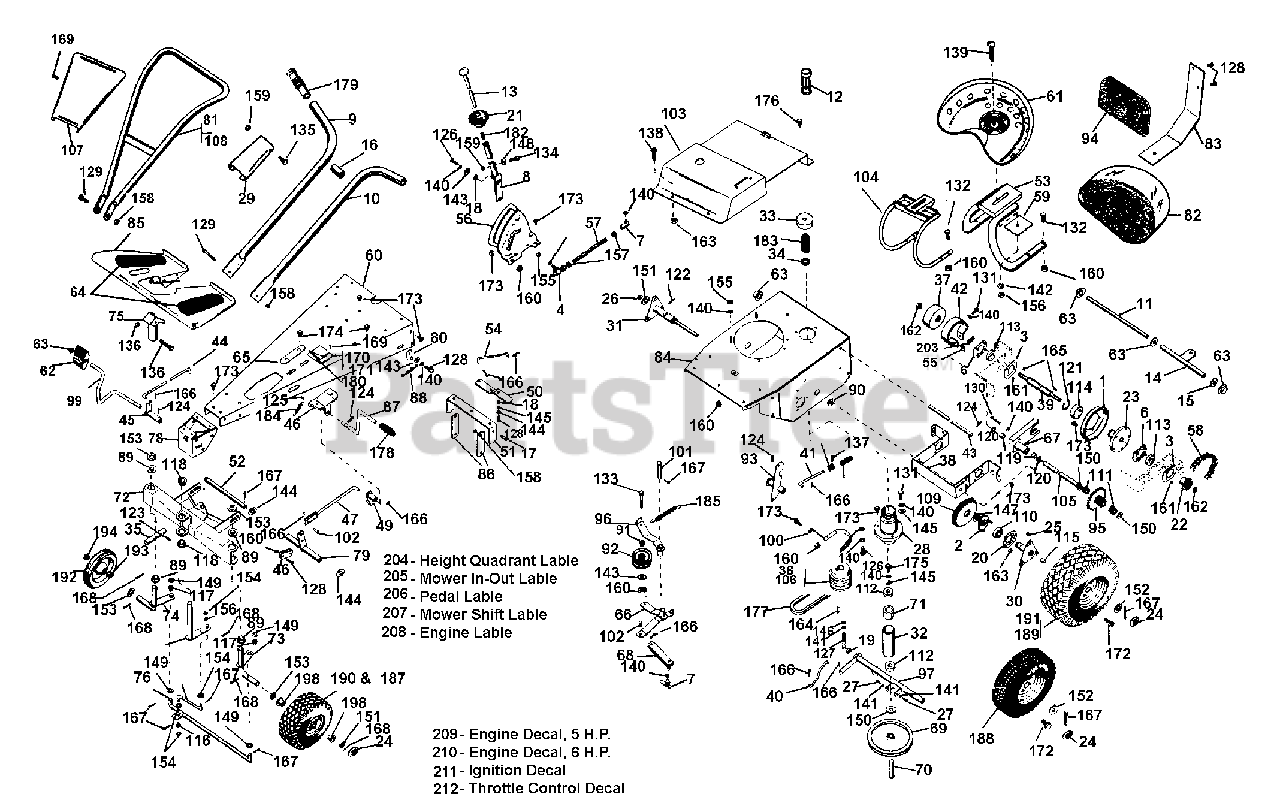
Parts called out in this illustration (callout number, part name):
1	FRICTION DISC
2	BEARING FLANGE
3	BEARING FLANGE
4	SNAP IN BALL JOINT
5	SET COLLAR
6	BEARING FLANGE
7	BALL JOINT
8	SHIFT LEVER
9	R H HANDLE BAR
10	L H HANDLE BAR
11	HITCH SHAFT
13	SHIFT RELEASE HANDLE
15	WAVE WASHER .531X.781X.125FH
16	SPACER
17	SHOULDER BOLT .50 X .281
18	SPACER BUSHING .5 X .32 X .21
19	FORK SPACER
20	BEARING FLANGE
21	SHIFT BALL
22	9 TOOTH SPROCKET
23	FRICTION DISC HUB
24	HUB CAP
25	HYDRAULIC DRIVE FITTING
26	PUSHNUT
27	SCREW PIN
28	DRIVE SPRING HOUSING
29	HNDLBR PANEL
30	L H AXLE
31	R H AXLE
32	DRIVE SPINDLE HOUSING
34	SPRING RETAINER
35	AXLE PIVOT PIN
37	BRAKE DRUM
38	CARRIER
39	HEX SHAFT
41	BRAKE ROD
42	BRAKE BAND
43	DISC FORK ROD
44	FRONT CLTCH ROD
46	FRONT LINK
47	MOWER CLTCH LINK
48	MOWER CLUTCH BRACKET
49	MOWER OVERCENTER LEVER
50	CLTCH TRANSFER LEVER
51	HANGER BRACKET
52	HANGER PIN
53	SEAT BRACKET
54	REAR CLTCH ROD
55	BRAKE BAND WASHER
56	SHIFT CNTL
57	SHIFT LINKS
58	CHAIN
59	SEAT SUPPORT WASHER
60	FRAME CHANNEL
61	SEAT
63	CAP, .50 ROD YWZC
64	FOOT PAD
65	GUIDE PLATE
66	SHIFT TRANSFER LEVER
67	SLIDING FORK
68	SHIFT LINK
69	DRIVE DISK
70	DRIVE SPINDLE
71	BEARING SPACER .87 X .63 X 1.2
72	FRONT AXLE ASSM
73	L H WHEEL SPINDLE
74	R H WHEEL SPINDLE
75	CENTER STEER COL
76	TIE ROD
77	STEER BLOCK
78	FRONT FRAME ASSM
79	MOWER CLUTCH LEVER
80	BLADE BRAKE
82	SEAT COVER
84	REAR FRAME
85	FOOT REST
86	HANGER LINK
87	MOWER CLTCH PEDAL
88	BRAKE RELEASE CHAIN
89	FLANGE BUSHING
90	FLANGE BUSHING
91	SPCR, BRG .315X.50X.688X.281
92	IDLER
93	BRAKE BELLCRNK
95	PINION & SPROCKET
96	IDLER ARM
98	STEERING LINK
100	REAR BELT FINGER
101	PIN-CLEVIS .500 X 3.250
102	CLEVIS PIN
105	CARRIER SHFT
106	ENGINE SHEAVE
109	DIFFERENTIAL ASSEMBLY
110	BRG-BALL ??X??X??
111	BRG-NEEDLE .625X.812X.50
112	BRG-BALL .625X1.375X.44
113	BRG-BALL .500X1.38X.437
114	BRG-BALL 1.25X2.18X.63
115	BSHG-SLV .562X.625X.625 BRZ
116	BSHG-FLG .372X.500X.312X.625NY
117	BSHG-FLG.500X.625X.312X.750NY
118	BSHG-FLG.750X1X.375X1.250 IC
119	BSHG-SLV .625X.750X.500 BR
120	SEAL .625X.875X.125
121	RG-RTNG-EXT 1.250X.050
122	PIN-ROLL .188X1.25
123	PIN-ROLL .250X1.25
124	PIN-ROLL .188X1.00
125	PIN-GRV .188X.75 TP G
126	BLT-HEX .31-18X1.00 PL GR 2
127	BLT-HEX .38-24X1.25 BLKO GR5
128	BLT-HEX .31-18X.75 PL GR2
129	BLT-HEX .38-16X2.50 PL GR2
130	BLT-HEX .31-24X.50 GR5
131	BLT-HEX .31-18X.50 PL GR2
132	BLT-HEX .31-18X1.50 PL GR2
133	BLT-HEX .31-18X1.25 PL GR2
134	BLT-HEX .25-20X1.25
135	BLT-HEX .25-20X2.75 PL GR2
136	BLT-HEX .25-20X1.50
137	SCR-SET .25-20X.50 SQHCUP HT
139	BLT-RDHDSQNK .50-13X1.25 PL
140	WSHR-LK .312X.097 PL HVY
141	WSHR-LK .375X.115 HVY PL
142	WSHR-LK .500X.151 HVY PL
143	WSHR-FL-STL .38X.875X.083 PL
144	WSHR-FL-STL .531X1.062X.095 PL
145	WSHR-FL-STL.312X.734X.065PL
146	WSHR-FL-STL .438X1.125X.19
147	WSHR-FL-STL .880X1.380X.062
148	WSHR-FL-STL .281X1.250X.048PL
149	WSHR-FL-STL .505X.875X.024 PL
150	WSHR-FL-STL .630X1.005X.062 PL
151	WSHR-FL-STL .755X2.000X.125
152	WSHR-FL-STL .568X2.000X.125
153	WSHR-FL-STL .755X1.375X.062 PL
154	WSHR-FL-STL .382X.812X.023 PL
155	NUT-HEX .312-18
156	NUT .50-13 PL
157	NUT-HEX .312-24 PL
158	NUT-LK-CTR .375-16 GR A PL
159	NUT-LK-CTR .250-20 PL
160	NUT-LK .312-18 GR A PL
161	NUT-KEPS 10-24 PL
162	NUT-LK-CTR .50-20 PL
163	NUT-LK-FLG .250-20 PL
164	KEY-WDRF .156X.625X.25 SAE 6
165	KEY-WDRF .125X.625X.250 SAE5
166	PIN-COTR .09X.75 PL
167	PIN-COTR .12X1.0 PL
168	PIN-COTR .12 X 1.25 PL
169	RVT-POP.125 X .294 DOME
171	THROTTLE CONTROL
172	BLT-WHL .50-20X.50 GR5 PL
173	BLT-SERHFWH .31-18X.50 PL
174	BLT-SCRHFWH .38-16X.50 PL
175	BLT-LK .31-18X.75 GR 5
177	V-BELT, SAE 380-RAW EDGE
179	GRIP
181	SG-COMP .1X.38X2.63 WLD 75
182	SG-COMP ??X.44X?? WLD 10
183	SG-COMP .148X1.25X2.53
184	SG-TENS ??X.25X1.31 WLD 12 `
185	SG-TENS .063X.44X2.81 WLD 18
186	SG-COMP .067X.562X1.75 WLD.34
188	TIRE & WHEEL ASSEMBLY CARLISLE
188	TIRE 4.10/3.50X6
188	TUBE
188	WHL 6 IN O.D.
192	WHL 10 IN O.D.
193	BSHG-FLG.750X1.125X1.000X1.250
194	BSHG-FLG.750X1.125X1.000X1.125
203	SPRING
204	HEIGHT QUADRANT LABEL
205	MOWER IN-OUT LABEL
206	PEDAL LABEL
207	MOWER SHIFT LABEL
208	ENGINE LABEL
